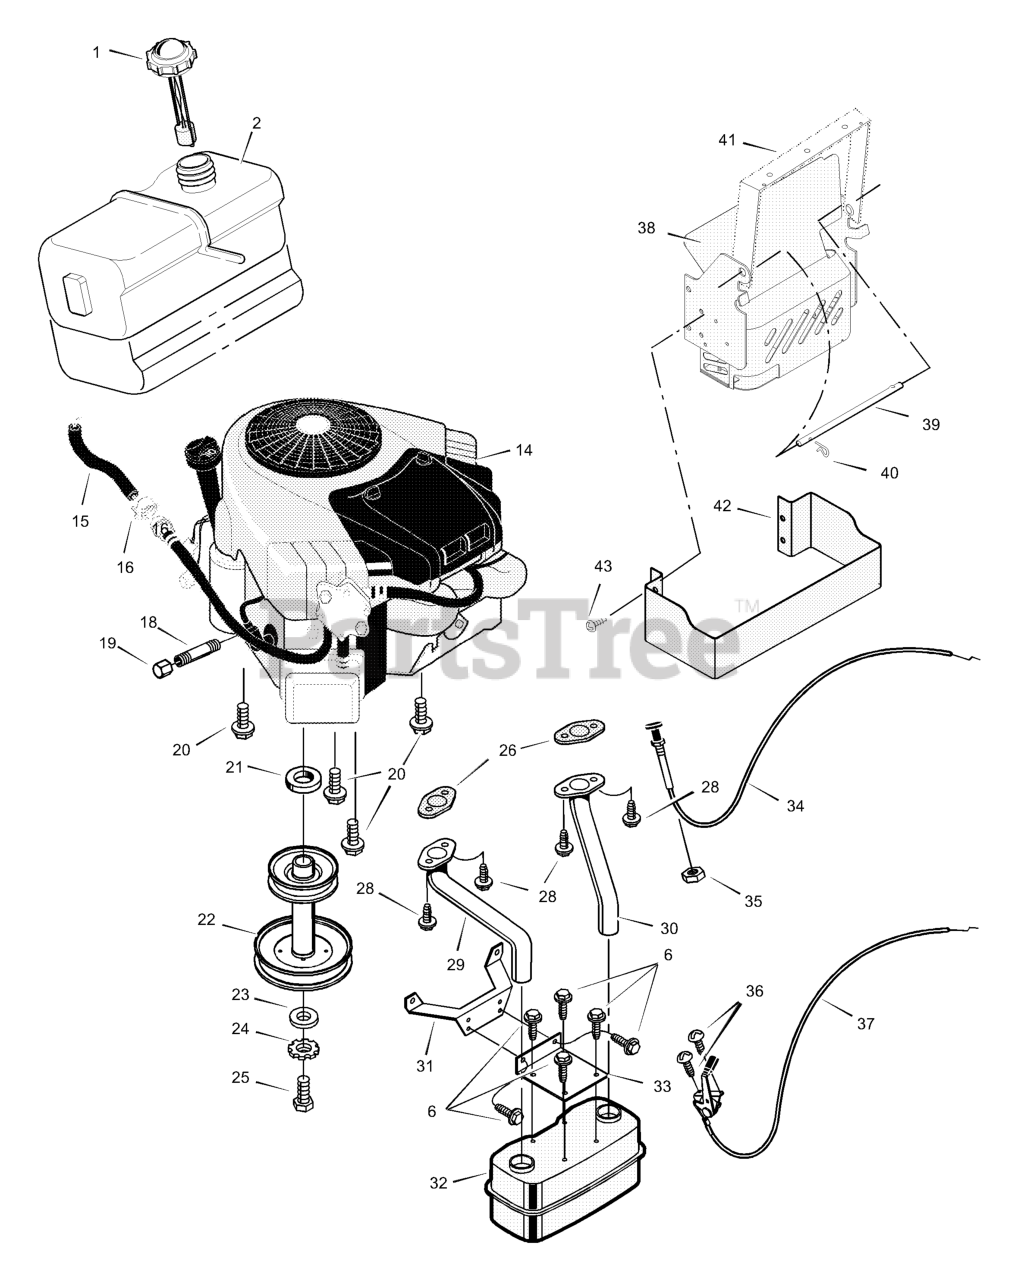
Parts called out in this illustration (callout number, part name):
1	Cap, Fuel
2	Tank, Fuel
14	Engine
15	Fuel Line (Must cut to length)
16	Clamp
18	Pipe, Oil Drain
19	Cap, Oil Drain
20	Bolt
22	Pulley, Stack
24	Lockwasher
29	Tube, Right Exhaust
30	Tube, Left Exhaust
31	Bracket, Muffler Mount
32	Muffler
33	Bracket, Muffler
35	Nut
37	Control, Throttle
38	Shield Assy., Heat -Twin
39	Rod, Pivot
40	Pin, Hair
41	Brace, Grille
42	GUARD, Heat Shield
